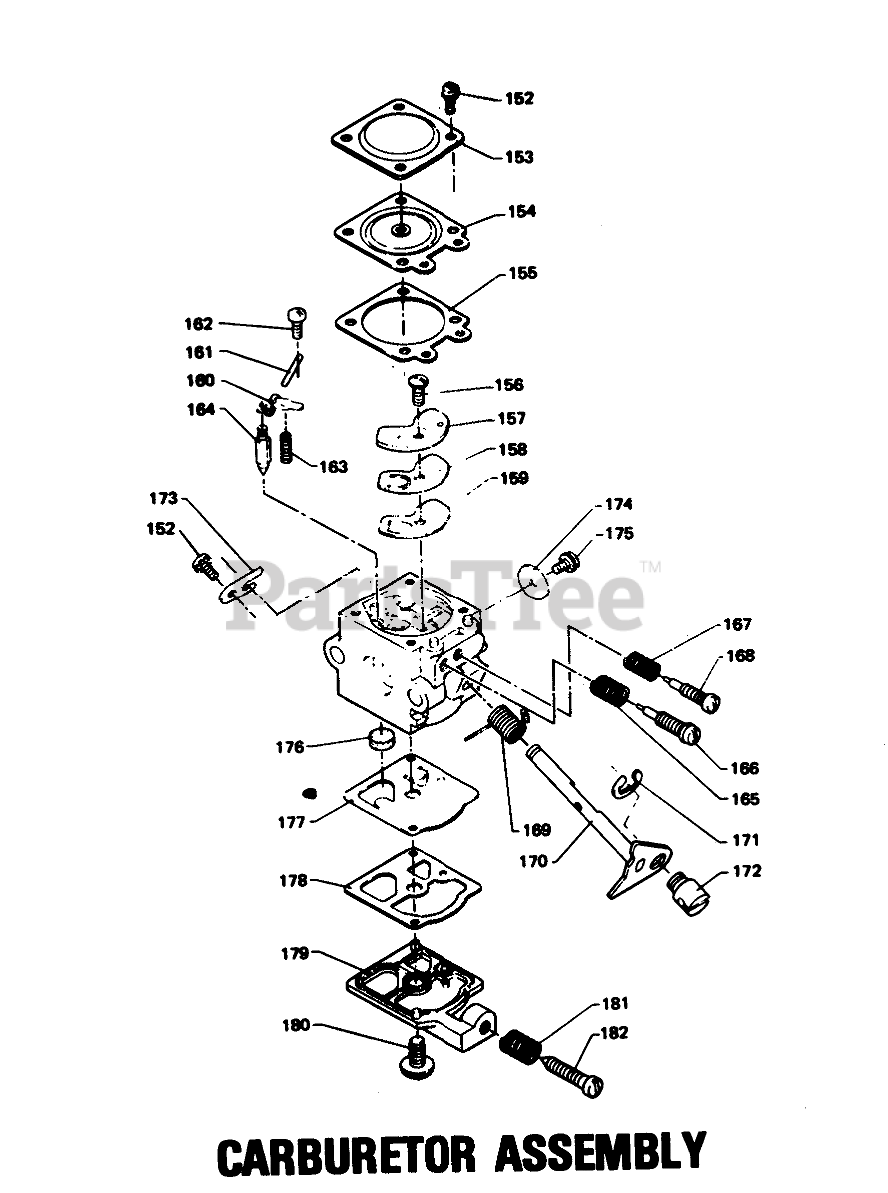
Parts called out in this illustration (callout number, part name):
152	Screw
153	Cover, Diaphragm
154	METERING DIAPHRAGM
155	Gasket, Diaphragm
156	Screw-Circuit Plate
157	Plate, Circuit
158	Diaphragm Circuit Plate
159	Gasket-Circuit Plate
160	Lever Metering
161	Metering Lever Pin
162	Screw-Metering Pin
163	METERING LEVER SPRING
164	INLET NEEDLE VALVE
165	Spring, HS Needle
166	Needle, HS
167	Spring, Needle
168	Needle-Idle
169	Spring-Throttle Lever
170	Shaft Ass-y. Throttle
172	Swivel
173	Clip Throttle Shaft
174	Valve-Throttle
175	Screw
176	Screen Inlet
177	Idler Arm
178	PUMP GASKET
179	Cover, Fuel Pump
180	Screw
181	Spring, Idle Screw
182	Screw, Idle Adjust
